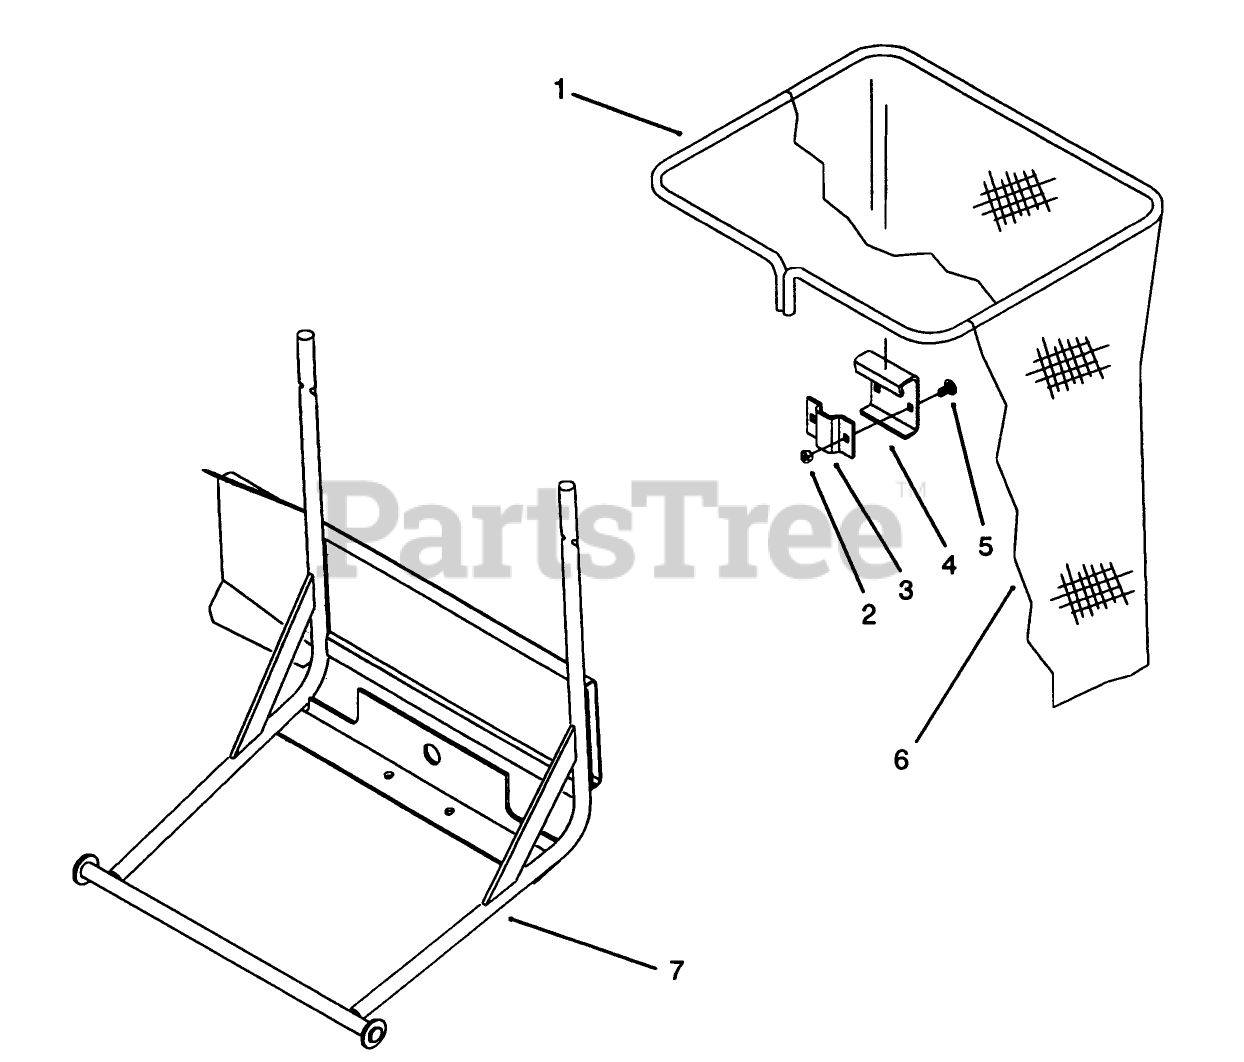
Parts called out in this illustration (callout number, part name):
2	NUT-LOCK, NI
5	BOLT-CARR
7	WLDMT-BAGGER RODS *B
